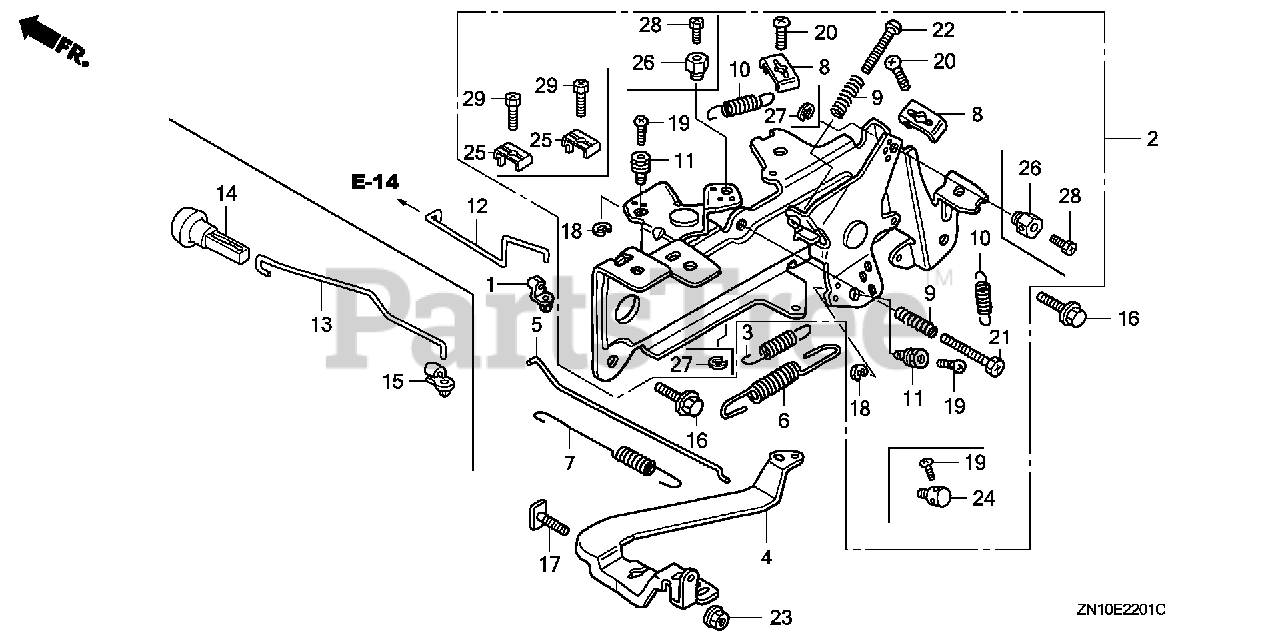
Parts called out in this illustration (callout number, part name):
1	JOINT, ROD
2	CONTROL ASSY.
3	SPRING, STARTER
4	ARM, GOVERNOR
5	ROD, GOVERNOR
6	SPRING, GOVERNOR
7	SPRING, THROTTLE RETURN
8	HOLDER, CABLE
9	SPRING, CONTROL ADJUSTING
10	SPRING, CABLE RETURN
11	HOLDER, WIRE
12	ROD, CHOKE CONTROL
16	BOLT, FLANGE (6X14) (CT200)
17	BOLT, GOVERNOR ARM
18	CIRCLIP (5MM)
19	BOLT, RECESSED (4X6)
20	BOLT, RECESSED (5X16)
21	BOLT, RECESSED (5X25)
22	SCREW, PAN (5X25)
23	NUT, FLANGE (6MM)
24	HOLDER, CABLE
